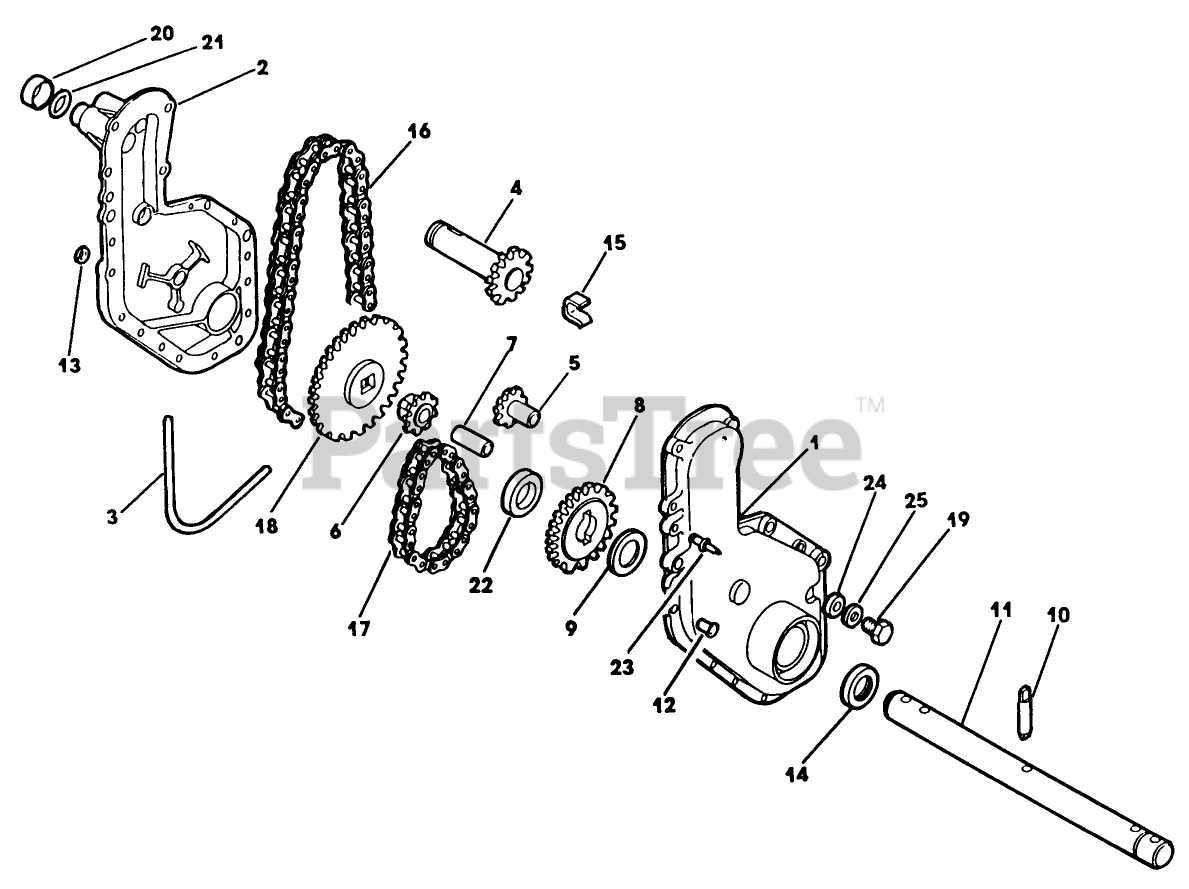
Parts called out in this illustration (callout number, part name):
3	GASKET
5	IDLER-SPROCKET
6	SPROCKET
8	SPROCKET - 27T
9	WASHER
11	AXLE
12	RIVET
14	SEAL
21	O-RING
